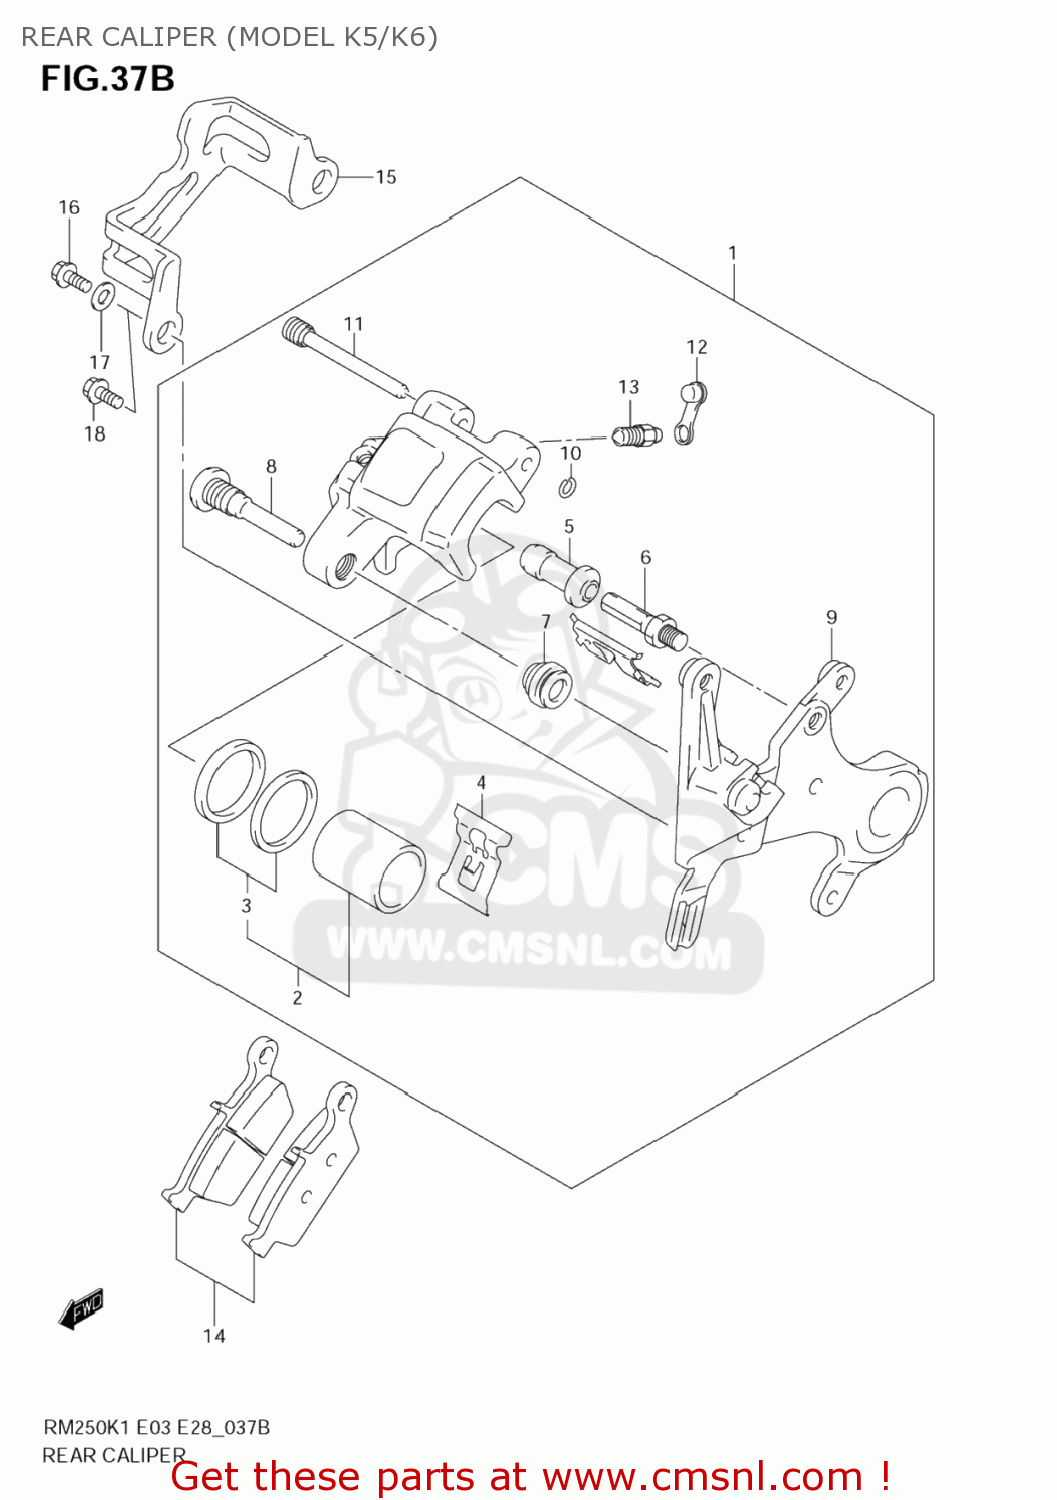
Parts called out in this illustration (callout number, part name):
1	CALIPER ASSY,RR
2	PISTON SET
3	SEAL SET,PISTON
4	SPRING,PAD
5	BOOT
6	BOLT
7	BOOT
8	PIN,BOLT
9	BRACKET
10	RING,STOPPER
11	PIN,HANGER
12	BLEEDER
13	CAP,BLEEDER
14	PAD SET (NAS)
15	GUARD,RR CALIP
16	BOLT(6X10)
17	WASHER
18	BOLT(6X12)
